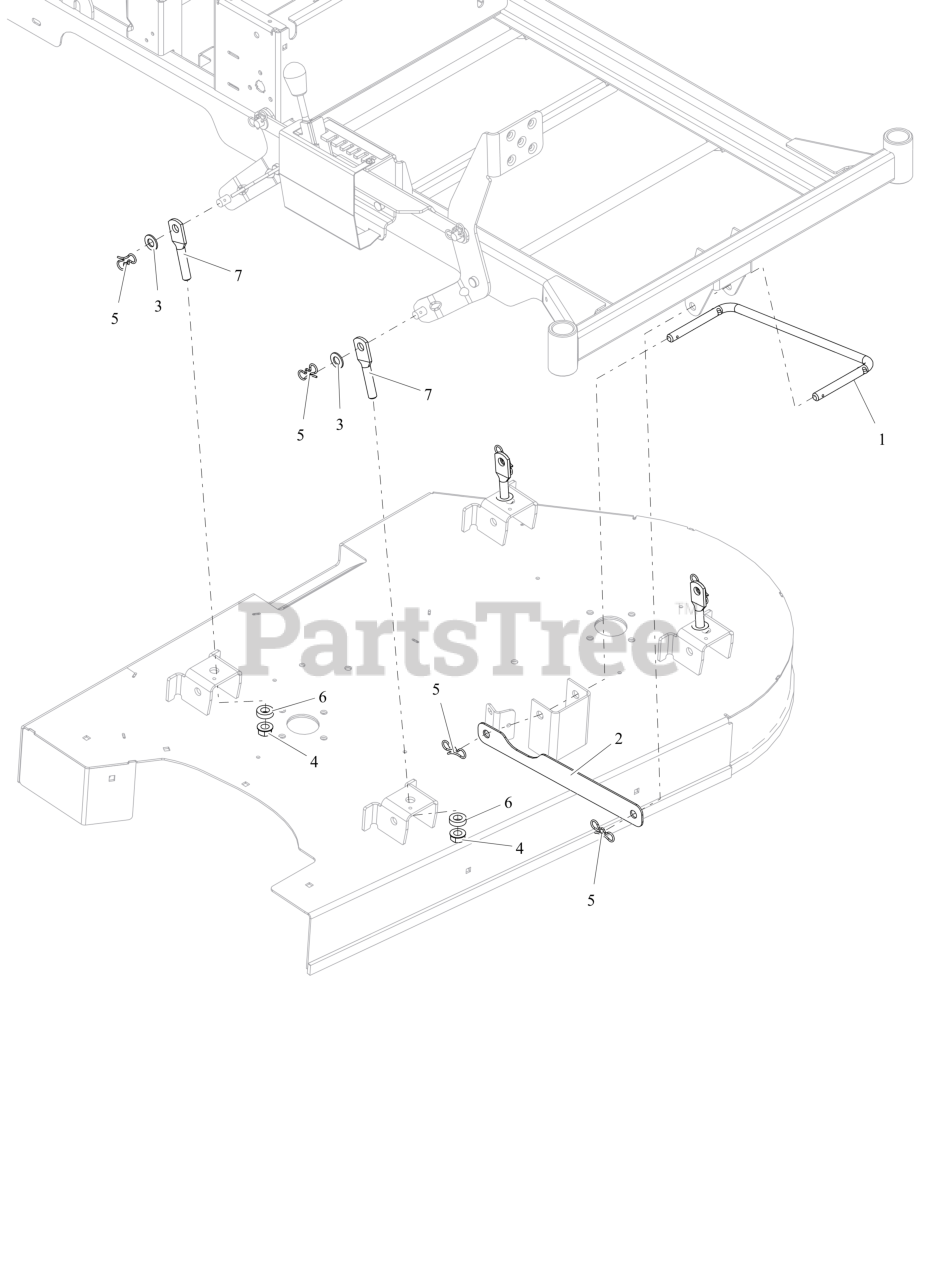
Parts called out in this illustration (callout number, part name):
1	WIREFORM, DRAG LINK
2	STRAP, DRAG LINK
3	WSHR-FL-NYL .518X1.000X.080
4	NUT-LK-CTR-FLG .500-13 GG ZCC
5	PIN, BOWTIE .091X1.875 ZCC
6	WASHER, RUBBER
7	LINK, DECK (HOLE-SHORT)
